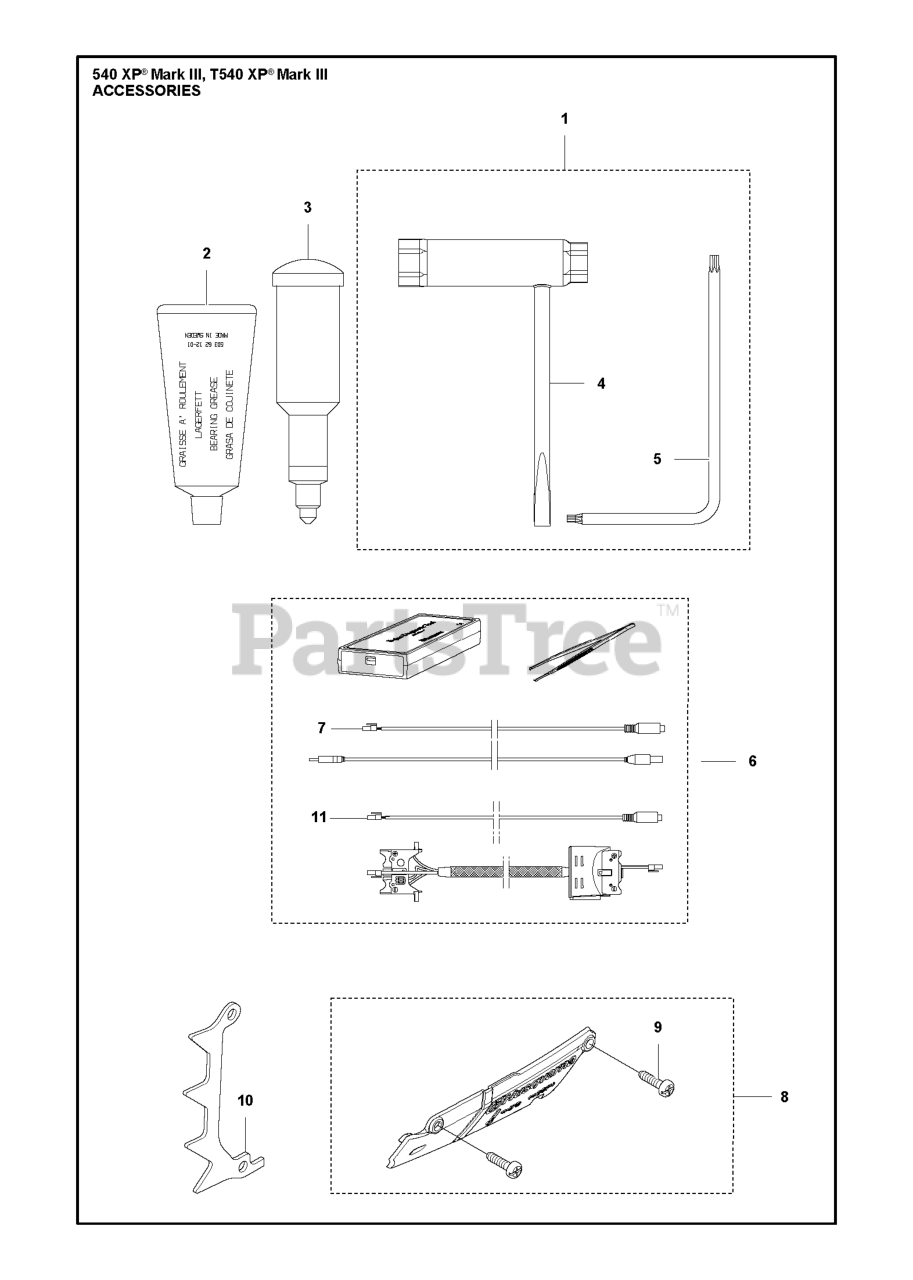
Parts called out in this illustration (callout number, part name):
2	GREASE
3	Grease Gun
4	COMBINATION WRENCH
6	DIAGNOSTIC TOOL KIT
7	CABLE ASSY
8	WINTER KIT
11	CABLE ASSY
